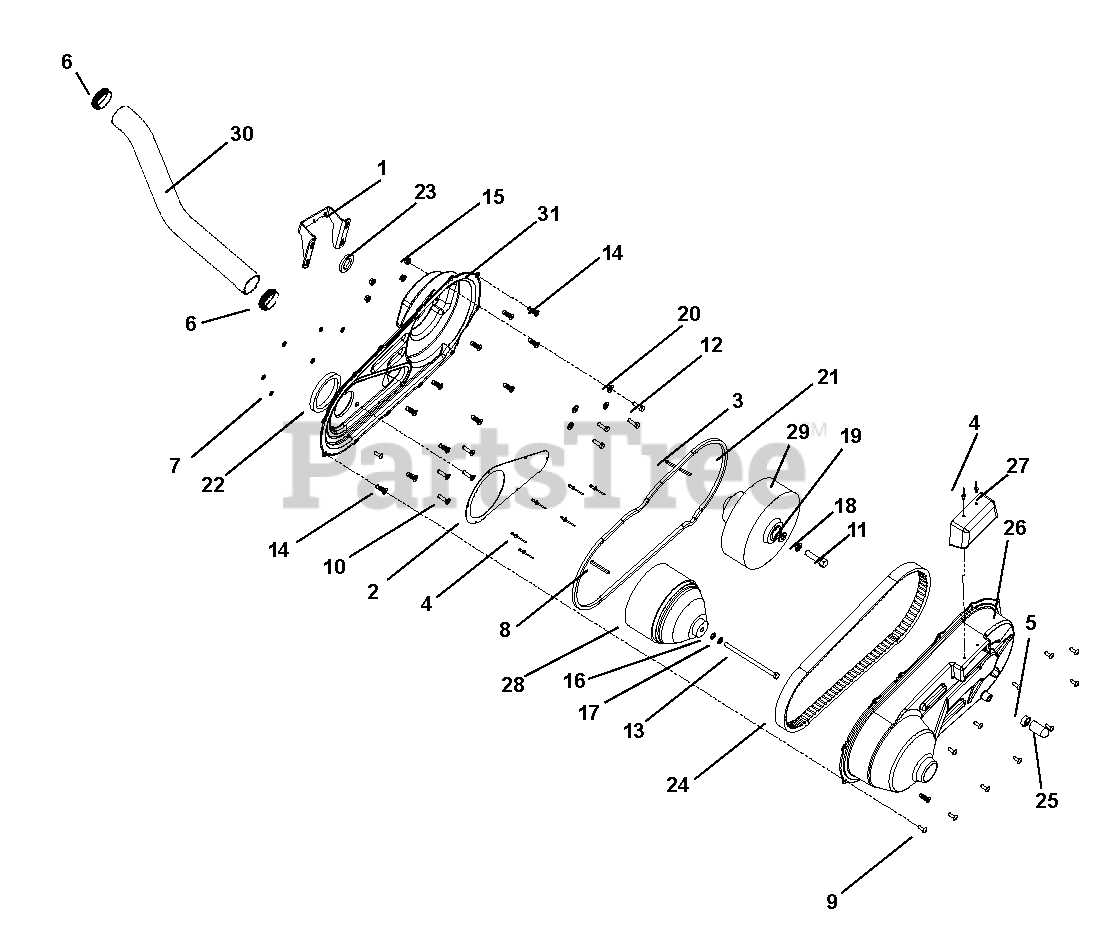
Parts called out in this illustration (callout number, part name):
1	BRACKET, CVT COVER TO TRANS.
2	COVER, CVT INLET DUCT
3	KEY 3/16 X 3
4	RIVET POP 3/16 .126-.250
5	SPRING CLAMP 1" OD HOSE
6	CLAMP, HOSE,WRM DRV,1.81 X 2.75
7	RIVET POP WASHER 3/16
8	KEY, .187 X .247 X 2.5 LG
9	SCREW, MCH .25-20 X .75 TXTR
10	BOLT, 5/16-24 X .75 HSFHCS (Apply Loc-Tite?)
11	BOLT, HEX .50-20 X 2.00 GR5 YWZC
12	BOLT, HEX .31-18 X 1 GR5 YWZC
13	HHCS 3/8-24 X 6 1/2 GR5 PLT
14	INSERT, 1/4-20 ARS4-420-280
15	NUT, TOP LOCK FLANGE .312-18 YWZC
16	WASHER, FLAT .406 X .812 X .065 YWZC
17	WASHER, LOCK .38 X .094 REG YWZC
18	WASHER, LOCK .50 X .125 YWZC
19	WASHER, FLAT .531 X 1.06 X .095 YWZC
20	WASHER, FLAT 5/16 NEOPRENE PLT
21	SEAL, MAIN TRUCK CVT HOUSING
22	GASKET, CVT, FOAM
23	SEAL, CVT TO TRANSAXLE
24	BELT, CVT – LP3
25	CAP, DRAIN 7/8 OD PORT
26	ENCLOSURE, CVT OUTER
27	OUTLET DIVERTER, CVT
28	DRIVER, POWERBLOC – LP3
29	DRIVEN, CVTECH POWERBLOC – LP3
30	HOSE, CVT AIR INTAKE
31	CVT SHROUD, INNER
